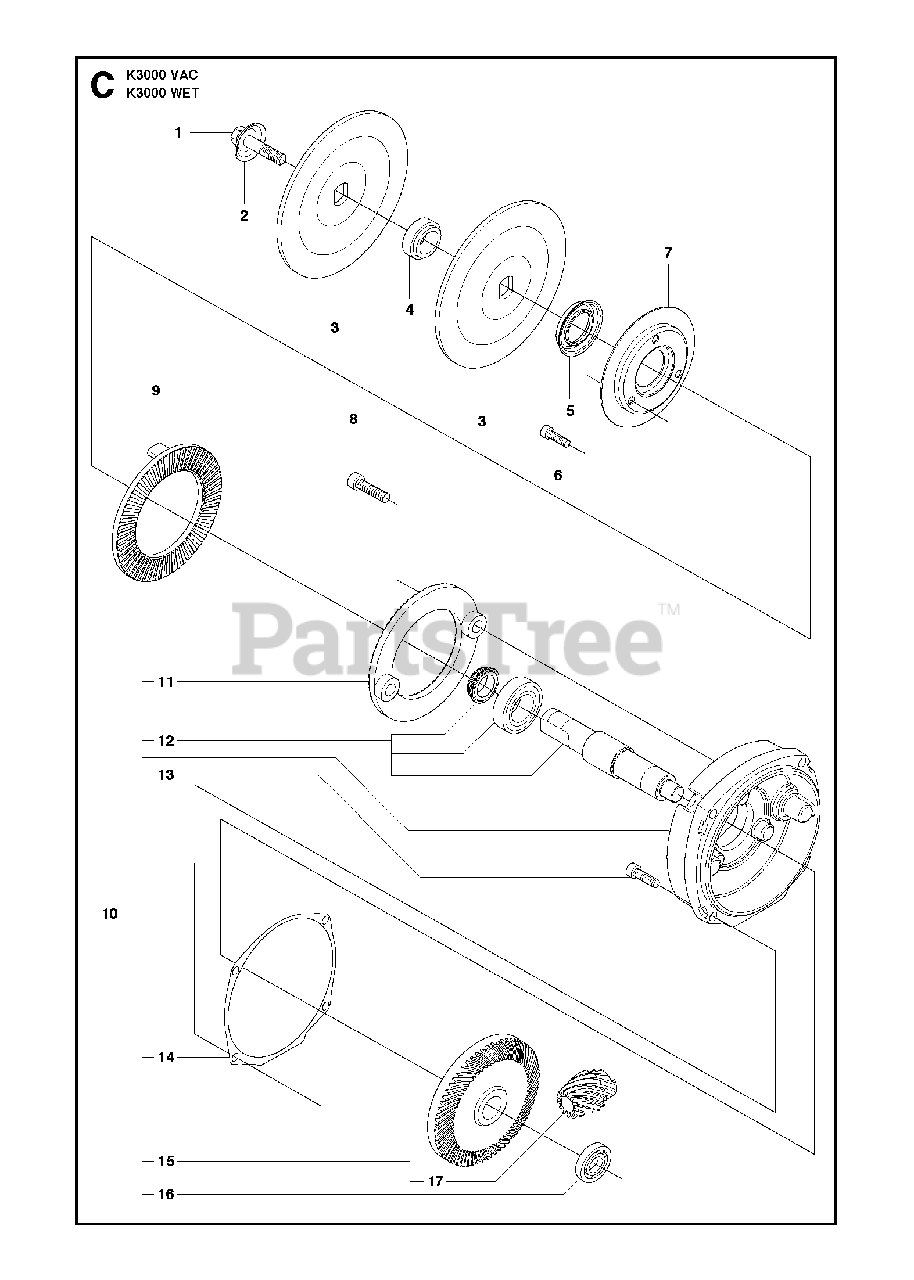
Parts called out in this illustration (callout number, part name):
3	FLANGE WASHERJP
4	KITDiam 20mm
4	KITDiam 22,2mm
4	KITDiam 25,4mm
4	BUSHINGDiam 30,5mm
6	SCREW ITXSCM
8	SCREW ITXSCM
10	GEAR SETIncl. 11 - 16
12	SHAFT
13	SCREW ITXSCM
15	GEAR WHEELIncl. 17
16	BALL BEARING
